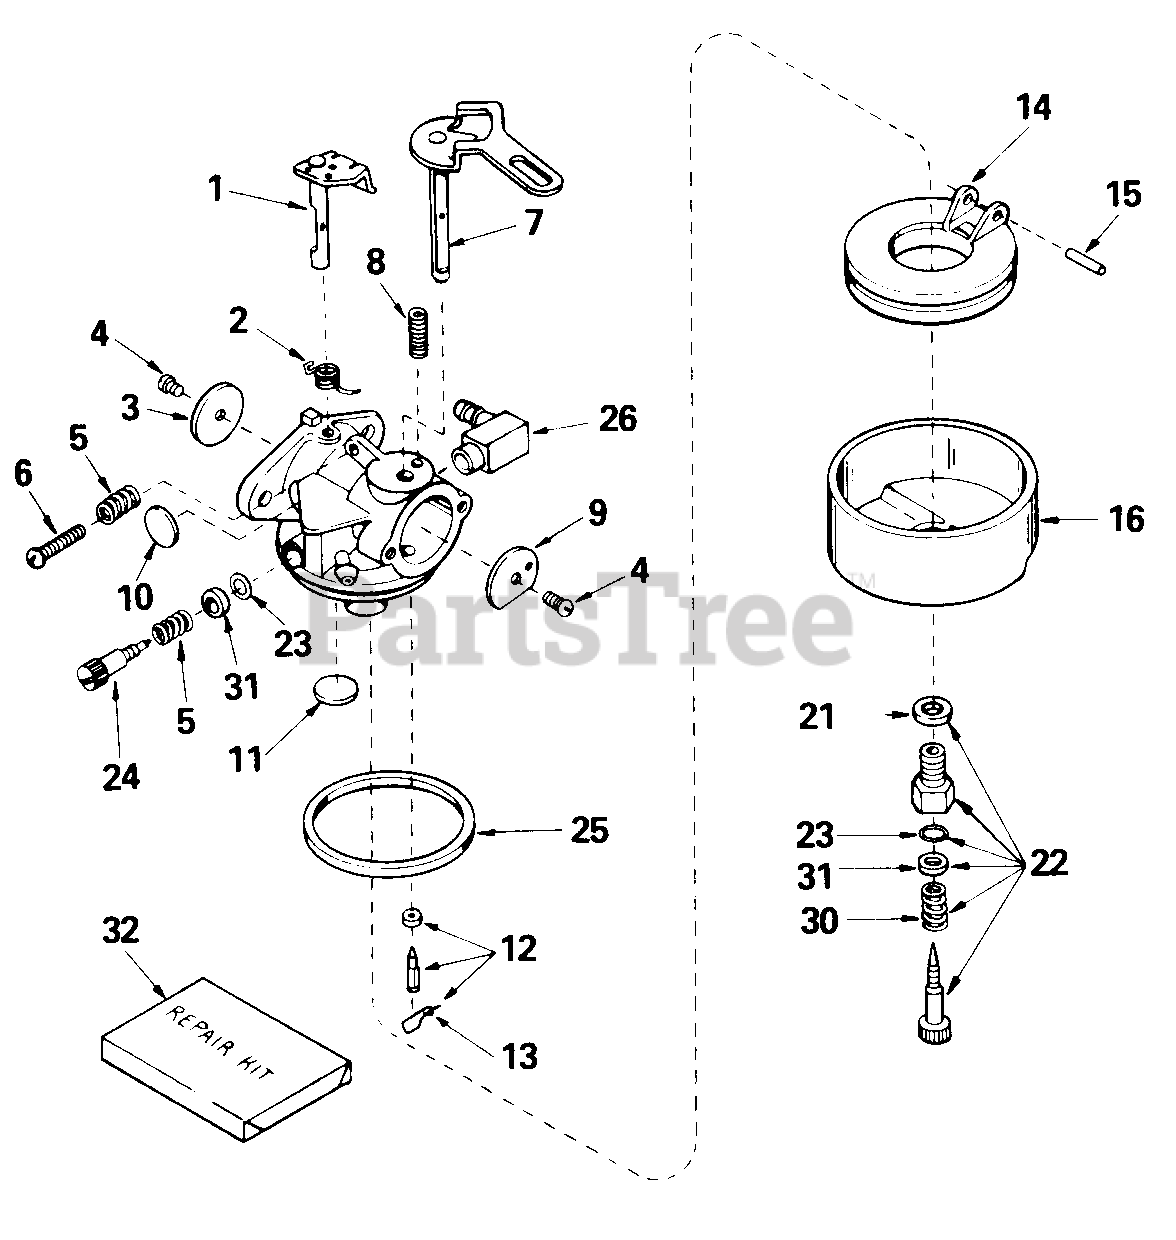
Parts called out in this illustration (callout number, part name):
1	Shaft & Lever Ass'y., Throttle
2	Spring, Throttle Return
3	Shutter, Throttle
4	Screw, 4-40 x 3/16
5	Spring, Idle Regulating Screw
6	Screw, Idle Regulating
7	Shaft & Lever Ass'y., Choke
8	Spring, Choke Stop
9	Shutter, Choke
10	Plug, Welch
11	Plug, Welch
12	Inlet Needle, Seat & Clip Ass'y.
13	Clip, Inlet Needle
14	Float, Carburetor
15	Shaft, Float
16	Bowl, Float
21	Gasket, Bowl-to-Body
22	Adjustment Screw Ass'y., Main
23	"O"-Ring, Adjustment Screw
24	Screw, Idle Adjustment
25	Gasket, Bowl-to-Body
26	Fitting, Fuel Inlet
30	Spring, Main Adjustment Screw
31	Washer, Flat
32	Repair Kit
